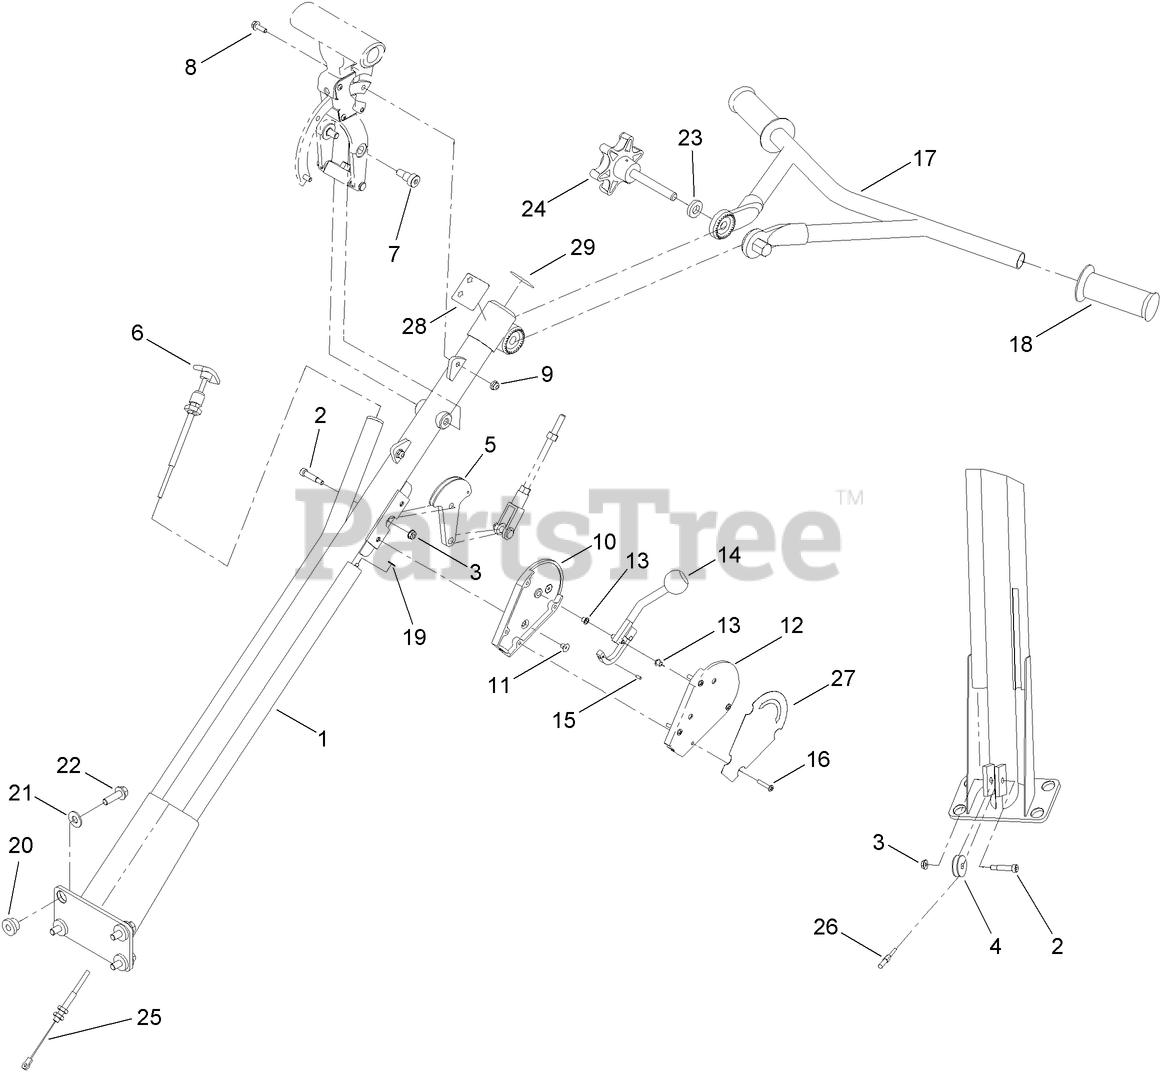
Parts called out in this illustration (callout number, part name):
1	HANDLE-COLUMN, MAIN
2	SCREW-HSBH
3	NUT-KEPS
4	PULLEY-PIVOT
5	CAM-CABLE, TILT PIVOT
6	CABLE-THROTTLE, PUSH/PULL
7	SCREW-HSBH
8	SCREW-HHF
9	NUT-HF
10	HOUSING-CLUTCH, DYNA
11	SCREW
12	COVER-CLUTCH
13	BUSHING-FLANGE
14	LEVER DYNA ASM
16	SCREW-PPH
17	HANDLE-ADJUSTMENT
18	GRIP-HANDLE
19	RING-EXTERNAL
20	MOUNT-SHOCK
21	WASHER-FLAT
22	SCREW-HHF
23	WASHER-FLAT
24	KNOB-ADJUSTMENT
25	CABLE-CLUTCH
26	CABLE-TILT
27	DECAL-DYNA CLUTCH
28	DECAL-RAISE, LOWER
29	DECAL-PRO PITCH
